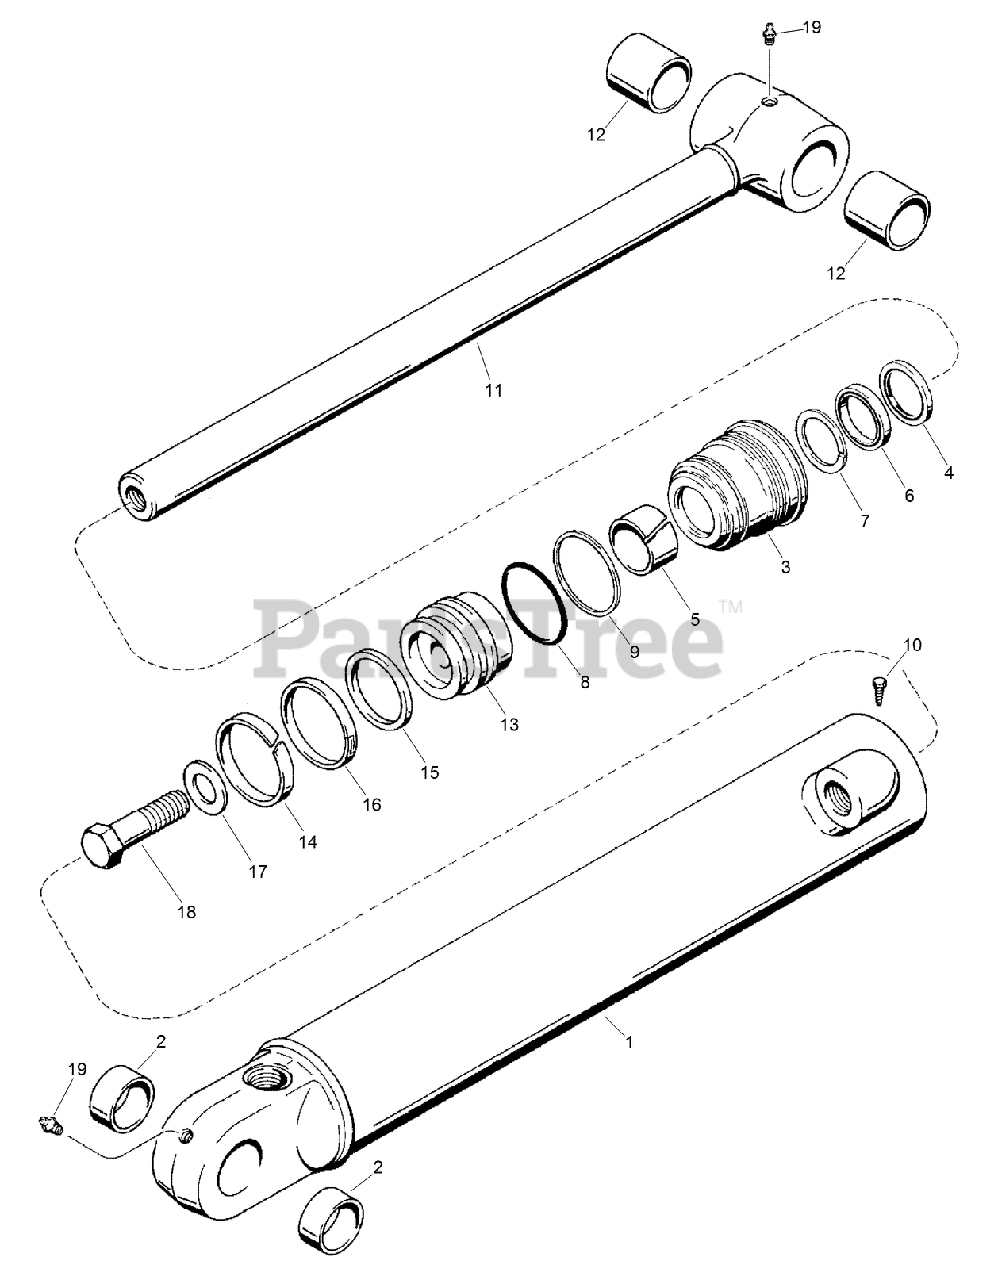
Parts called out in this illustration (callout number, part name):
1	TUBE-Cylinder
2	BUSHING
4	WIPER
5	RING-WEAR
6	CUP-U
7	SEAL-BUFFER
8	O-RING
9	RING-BACK-UP
10	SCREW-Self-Tapping, Hex Head
11	ROD-PISTON
12	BUSHING
14	RING-WEAR
15	EXPANDER
16	SEAL-PISTON
17	WASHER-Flat
18	BOLT-Hex
19	FITTING-Lube 1/8-27 Dryseal PTF
